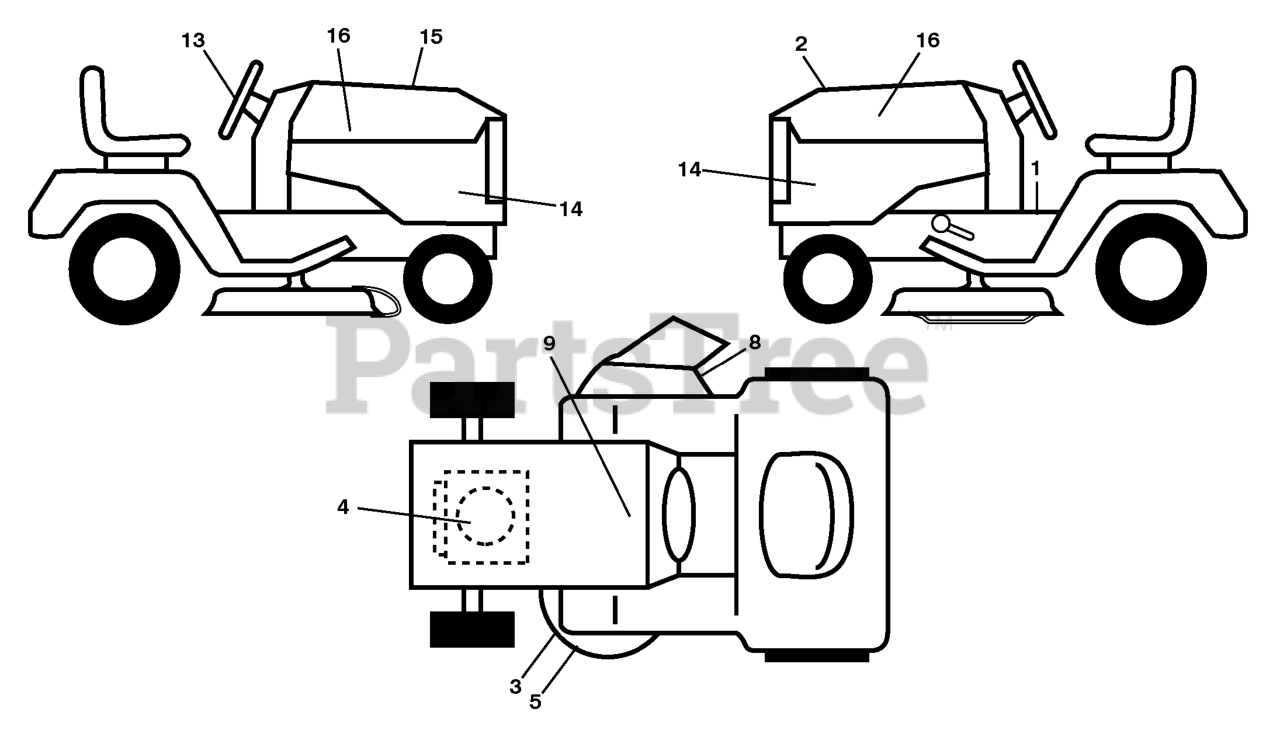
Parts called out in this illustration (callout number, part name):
1	DECAL.FENDER.OPER.TEX.
2	DECAL.HOOD.TOP.INSERT.
3	DECAL.WARN.KEEP.HAND.AWAY
4	DECAL, ENGINE, HP
5	DECAL CLUTCH/BRAKE
8	DECAL.MOWER.SCH.48/54
9	DECAL BTRY SYMBOLS
13	DECAL.WHEEL.STRG.LGN.H
14	DECAL PANEL
15	DECAL HOOD CUST. RESP.
16	DECAL.HOOD.NAMELOGO.HUSQ
17	DECAL REPLACEMENT
17	DECAL.BYPASS.FENDER.CRD.LT.YT
